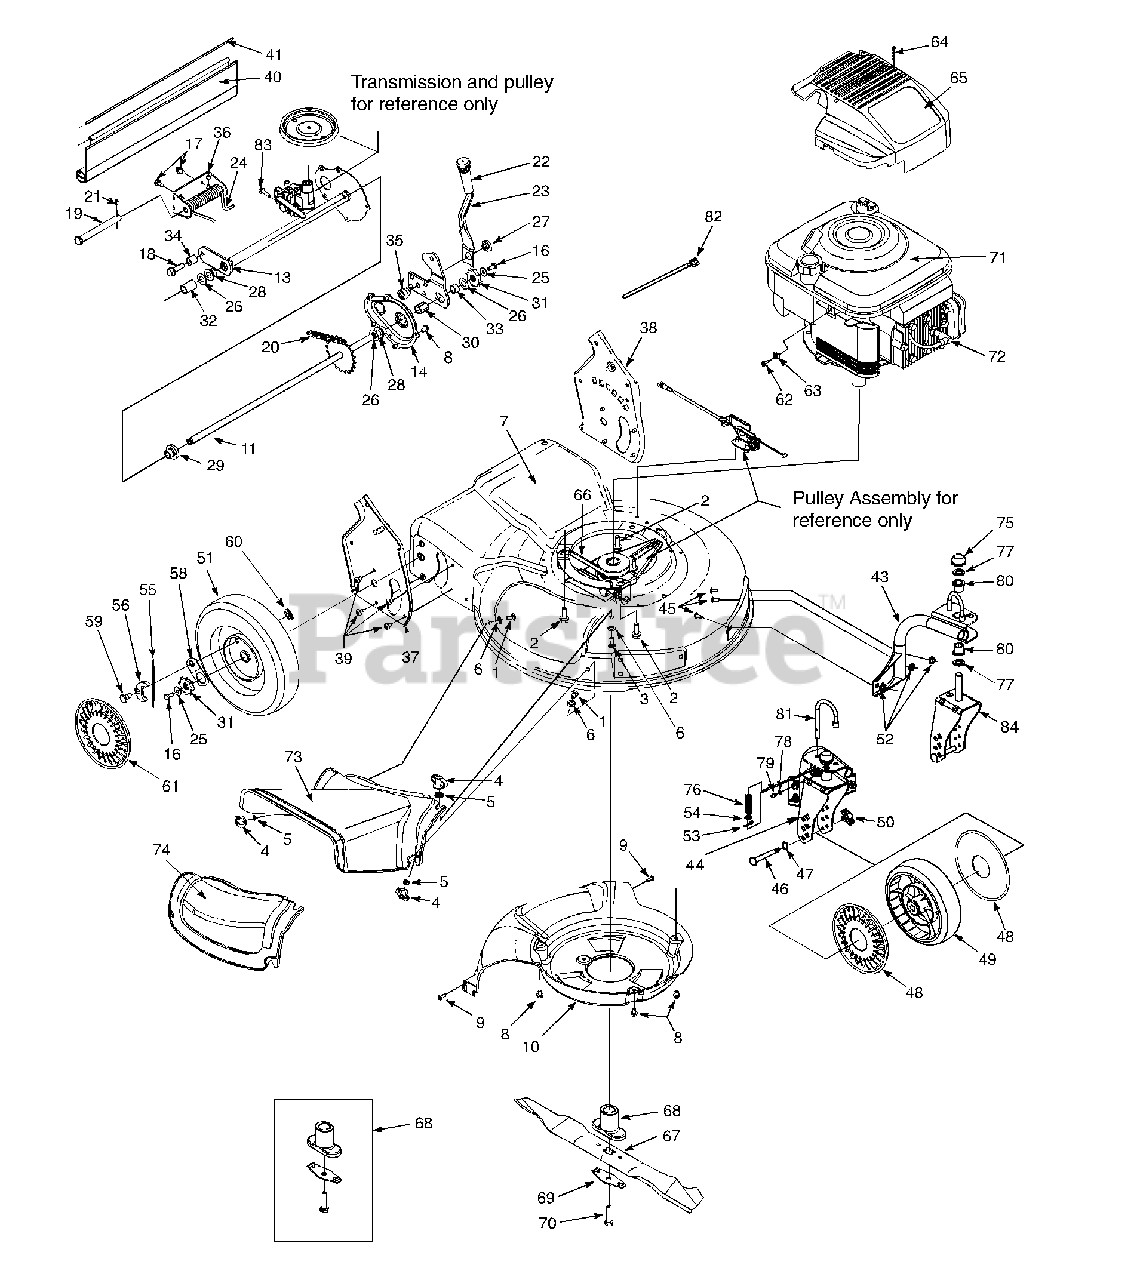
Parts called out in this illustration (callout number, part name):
1	Scr. Carr. 1/4-20 x .62
2	Scr. TT:3/8-18:1.00
3	Scr. 1/4-20 x .750
4	Wing Nut 1/4-20
5	Nut, Push .25 I.D. x .50 O.D.
6	Wash. Fl. .334 I.D.x .62 x.03
7	Deck - 21"
8	Scr. TT. 1/4-20 x .375
9	Scr. Truss Machine TT
10	Baffle
11	Rear Axle Ass'y
17	Scr. AB 1/4-14 x .825
18	Scr. 3/8 116 x .25
19	Clevis Pin .50 Dia. x 4.82
20	Chain-Endls.
21	Cotter Pin .125 O.D. x .75
23	Spring Lever
24	Torsion Spring
25	Bell Wash. .285 x .75 x .082
26	Fl. Wash.. 508 I.D.
27	Nut Shld. .825 Dia. x .165
28	Hx.Flg. Brg..506 I.D. x .590
29	Hx.Flg. Brg. .506 I.D. x.715
30	Hx. Slv. Brg. .504 I.D. x .830
31	Wheel Rachet
32	Spa. .550 I.D. x /750 O.D.
33	Spa. .51 .D. x .70 O.D. x 38
34	Spa. .385 x .624 x .700
35	Shld. Spa. .385 I.D. X .715
38	Handle Brkt. Assembly L.H.
39	Scr. AB 1/4-14 x .500
40	Trail Shield
41	Trail Shield Wire
43	Caster Ass'y L.H.
44	Brkt. Ass'y, Wheel Caster RH
45	Carr. Bolt 5/16-18 x .62
46	Caster Axle .374 Dia. x 2.50"
47	Wave Wash.
48	Hub Cap Whole Gray
49	Wheel 7 x 2, Caster Black
50	Wing Nut 1/4-20 Thd.
51	Wheel 9 x 2 Link Gray,
52	Lock Nut 5/16-18
53	Pin, Cotter .072 x 1.12
54	Fl. Wash. .330 x .830 x .06
55	Spring, Ratchet, Plastic
56	Pawl - R.H.
58	Ratchet Pawl Plate
59	Shld. Scr. .340 x .285
60	Top Lock Weld Nut 1/4-20
61	Hubcap - Gray
62	Screw .620 Hx. Slt. Wsh.
63	Casing Clamp, Throttle
64	Scr. Hi-Lo #10 x 1.25
65	Shroud - Gray
66	Belt
67	21" Mulching Blade
68	Blade Adapter Kit
69	Blade Bell Support
70	Hex Bolt 3/8-24 x 2.5" Lg.
71	Engine
72	Spark Plug Insulator
73	Side Discharge Chute
74	Mulch Cover
76	Compression Spring
77	Fl. Wash. 5/8 O.D. x 1" O.D.
78	Fl. Wash. .203 I.D. x .403
79	Fitting - Lube
80	Flange Bearing
81	Lock Pin: Front Wheel
82	Cable Tie
83	Hex Scr. 5/16-18
84	Brkt Ass'y, Wheel Caster LH
